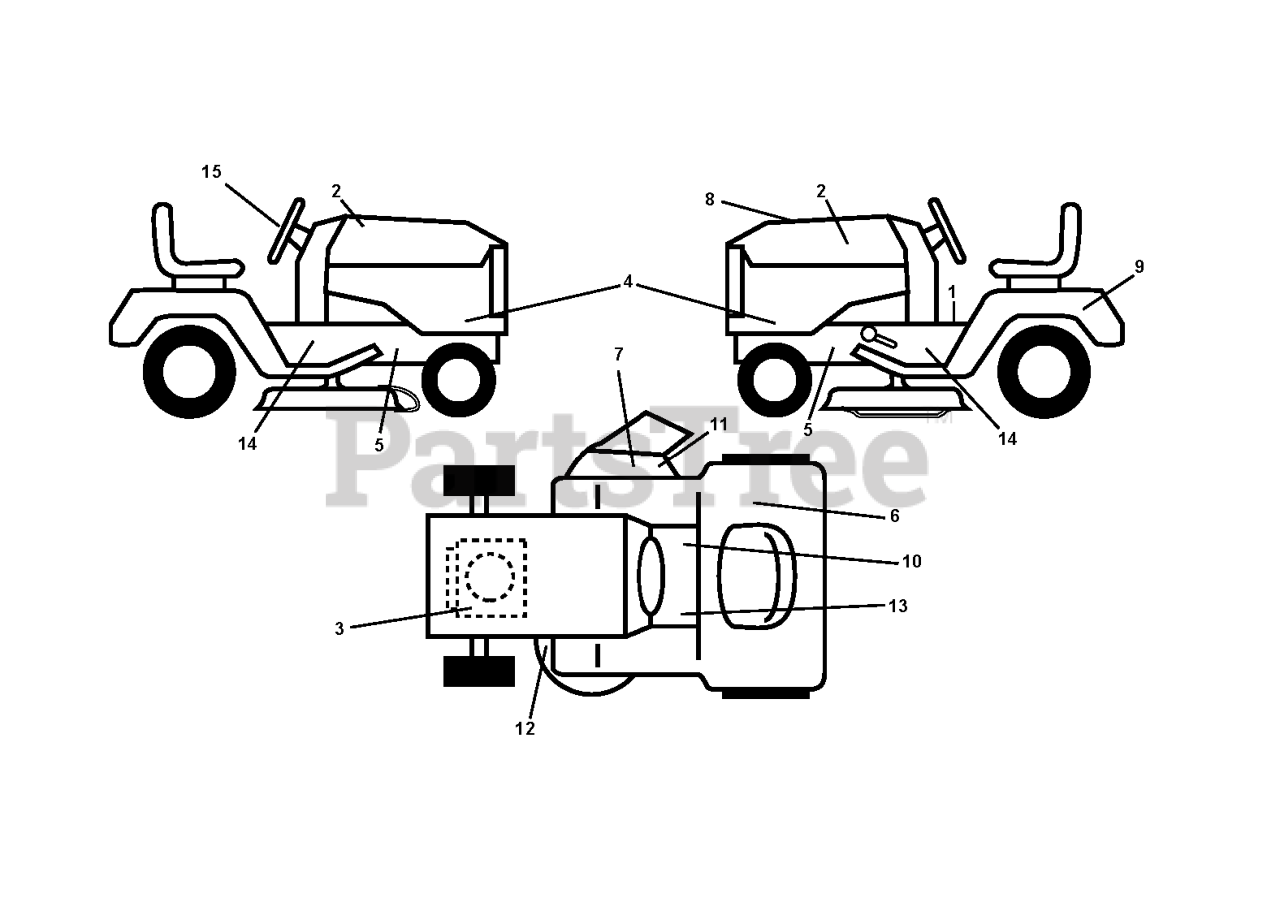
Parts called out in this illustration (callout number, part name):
1	LABEL
2	DECAL.HOOD.NAMELOGO.HUSQ
3	DECAL
6	Decal, Fender 100 DB/CE
7	DECAL.INTERNATIONL.CUTFINGER
9	DECAL BTRY SYMBOLS
10	DECAL PARK BRAKE
11	DECAL, DEFLECT WARNING
12	DECAL V BELT SCHEMATIC
13	DECAL
15	DECAL.WHEEL.STRG.LGN.H
